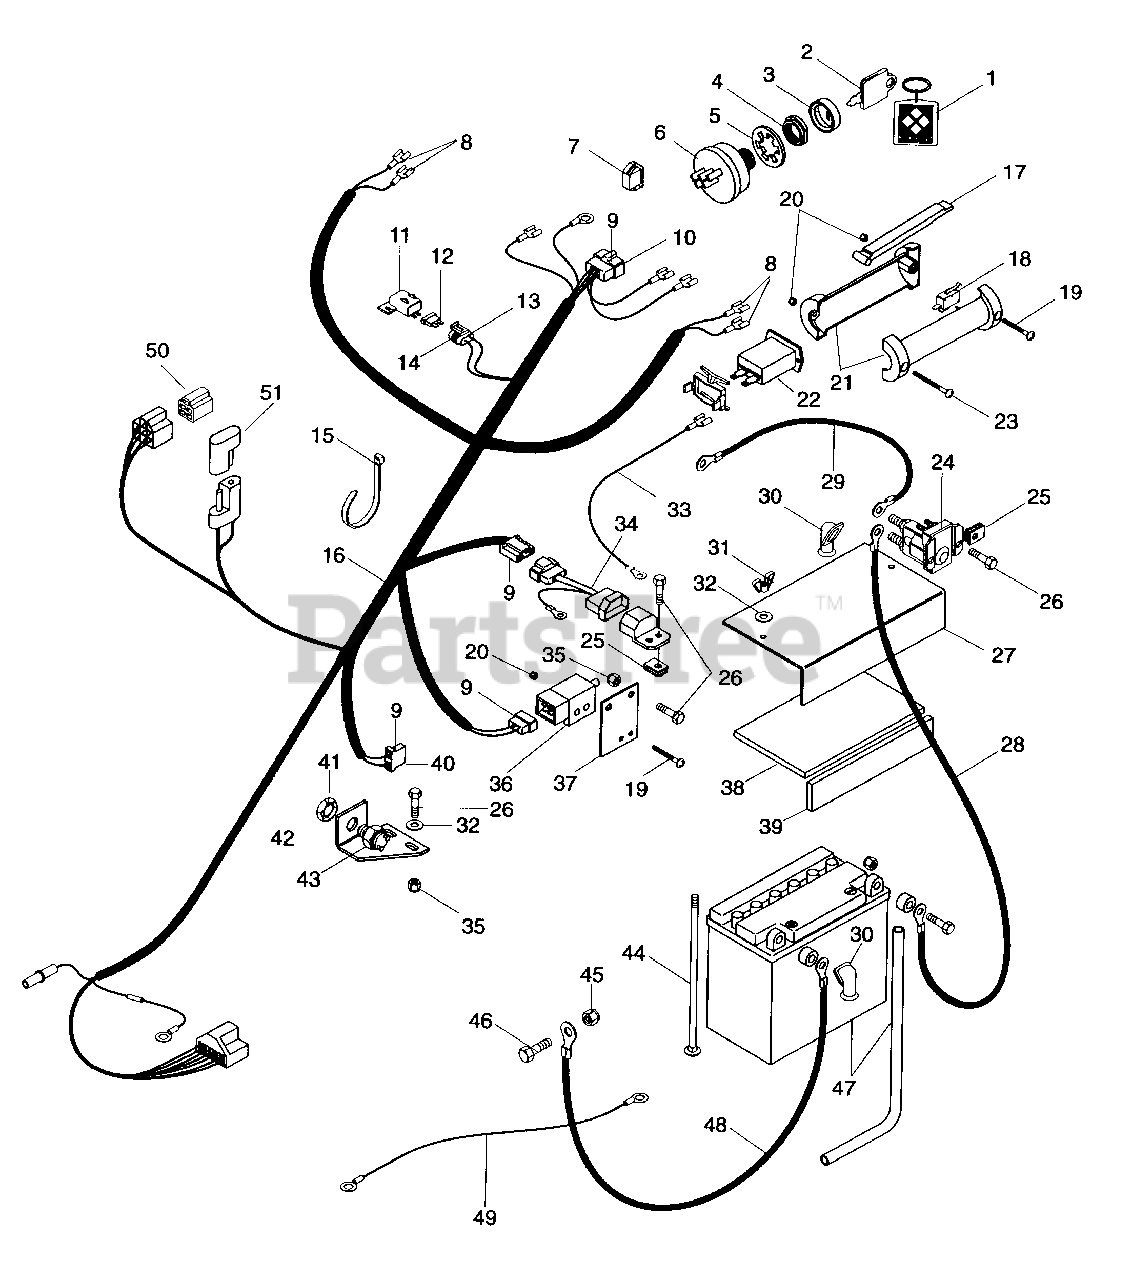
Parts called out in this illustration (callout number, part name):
1	Key Chain
2	Ignition Switch Key
3	Cap - Ignition Switch
4	Nut-Panel .625-32
5	Washer Lock .625
6	Ignition Switch Assembly
7	Light, Indicator
8	Terminal, Female
9	Terminal
10	Connector
11	Cover
12	Fuse, 25 AMP
13	Assembly, Connector, Weather Tight
14	Terminal, For 10-12 Gauge Wire
15	Tie Wrap, Black
16	Harness, Wiring, 20-HP Kohler
17	Lever
18	Switch
19	Screw-Machine 10-24 x .625
20	Nut-Locking 10-24 Nylon
21	Handle
22	Hour Meter
23	Screw-Machine 10-24 x 1.50
24	Solenoid
25	Nut-Speed .25-20
26	Bolt-Hex .25-20 x .75 Grade 5
27	Cover, Battery
28	Cable, Battery to Solenoid
29	Cable, Starter
30	Boot, Insulator
31	Nut-Wing .250-20
32	Washer-Flat-Steel .281 x .625 x .065
33	Wire, Instrument Panel
34	Kit, Interlock Module, Electric
35	Nut-Locking-Nylon .250-20 w/Insert Grade 2
36	Switch, Interlock
37	Bracket, Interlock Switch
38	Pad, Battery
39	Pad, Battery
40	Connector, 2-Wire Switch
41	Nut-Stamped .56-18
42	Bracket, interlock Switch
43	Switch-Neutral Start N.O.
44	Bolt-Round Head Square Neck .25-20 x 7.00
45	Nut-Locking Nylon .312-18 w/Insert Grade 2
46	Bolt-Hex .31-18 x 1.00 Grade 5
47	Battery, 12 Volt
48	Cable, Negative Battery
49	Wire, Ground
51	Molded Diode Plug - Clear 1 AMP
